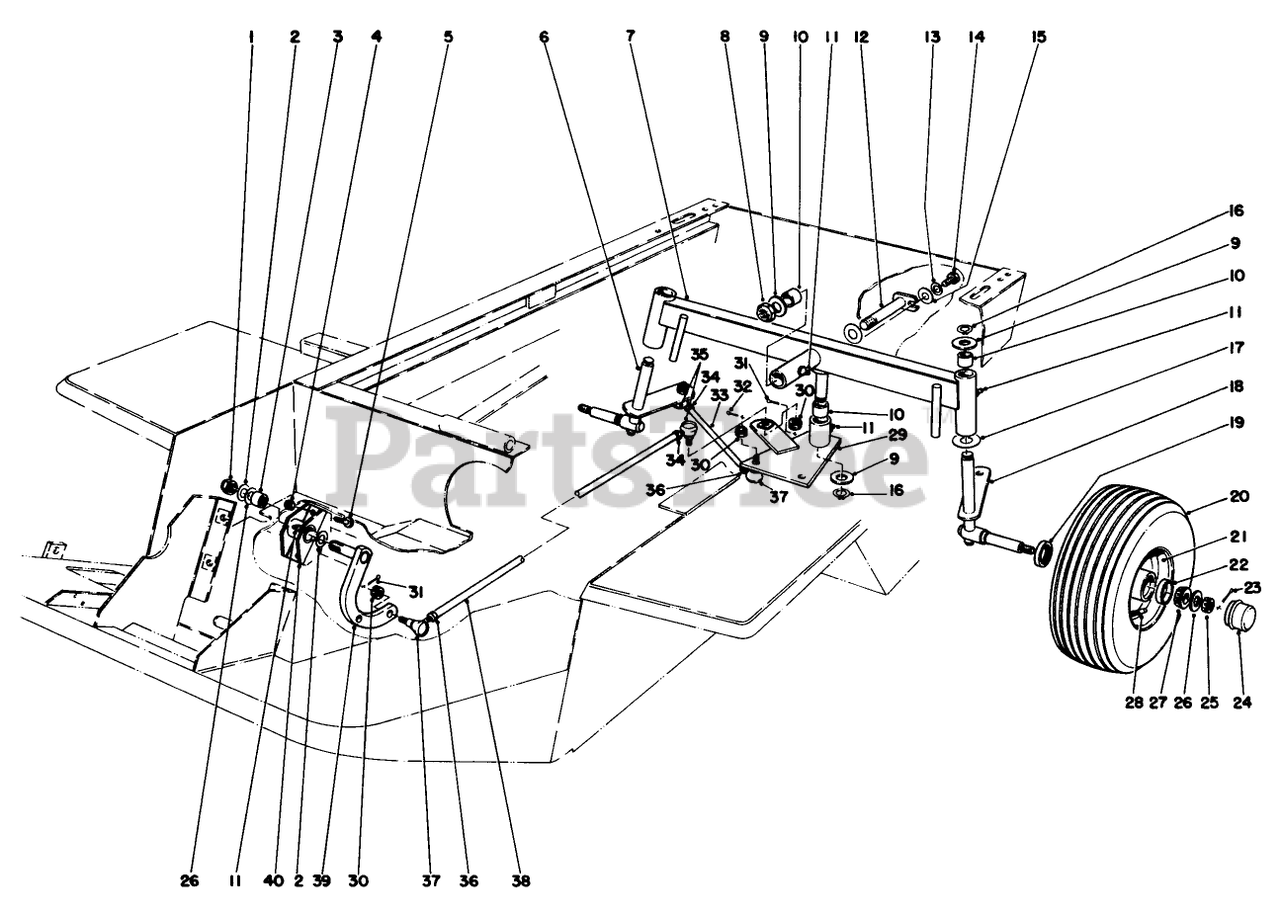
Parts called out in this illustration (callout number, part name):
1	NUT-LOCK, NI
2	THRUST WASHER
3	BEARING-NEEDLE
4	NUT-LOCK, NI
5	SCREW-HH
6	Spindle R.H.
7	Axle-Rear (Incl. Ref. #10 & 11)
8	NUT-LOCK, NI
9	WASHER-THRUST
10	BUSHING
11	FITTING-GREASE
12	Pin-RearAxle
13	WASHER-LOCK
14	SCREW-HH
15	WASHER-FLAT
16	RING-RETAINING
17	WASHER-THRUST
18	Spindle L.H.
20	TIRE 4 PLY
21	Rim (Incl. Ref. #22)
22	BEARING-CUP, TAPERED
23	PIN-COTTER
24	CAP-DUST
25	NUT-HEX, SLOTTED
26	WASHER-FLAT
27	BEARING-CONE, TAPERED
28	VALVE STEM AND CAP ASM
29	Plate-Steering (Incl. Ref. #10 & 11)
30	NUT-SLOTTED
31	PIN-COTTER
32	PIN-COTTER
33	STRG TIE ROD R
34	NUT-HJ (LH THREAD)
35	Assembly-Socket, L.H. (Incl. Ref. #30)
36	NUT-JAM
37	Assembly-Socket, R.H. (Incl. Ref. #30)
38	REAR STRG TUBE PP
39	PIVOT ARM WA
40	Mount-Pivot (Incl. Ref. #3 & 11)
